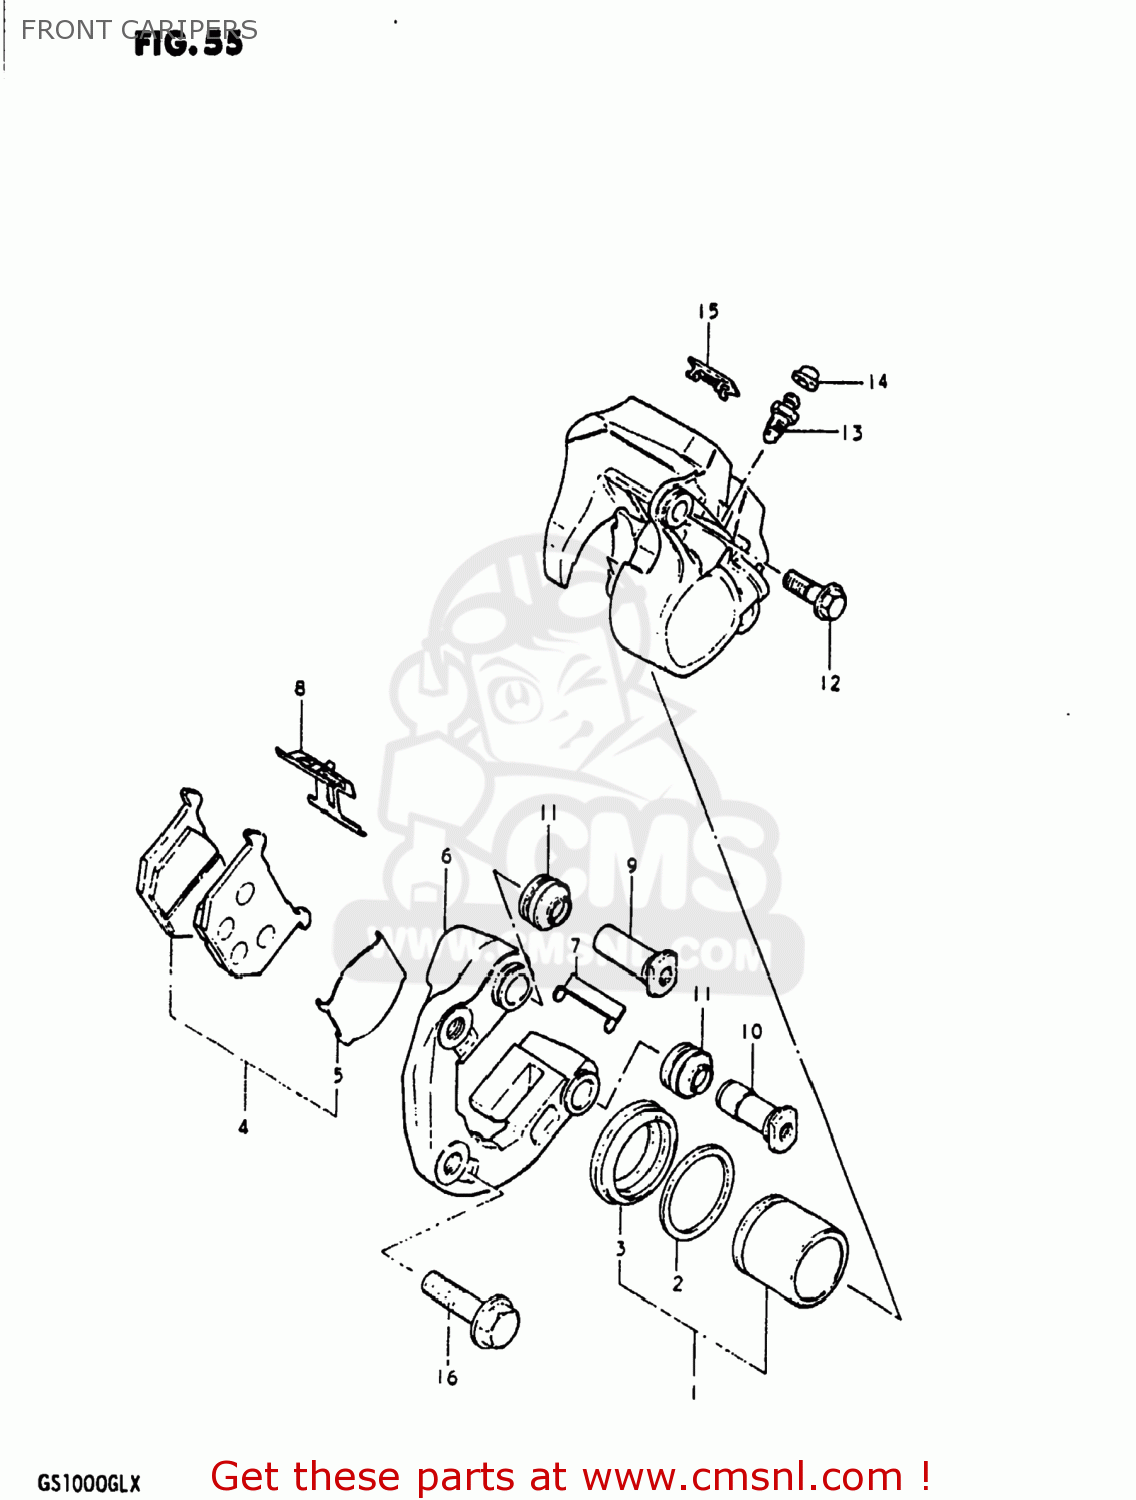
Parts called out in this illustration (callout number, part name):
0	CARIPER ASSEMBLY,RIGHT
1	PISTON SET
2	SEAL,PISTON
3	BOOT,PISTON
4	PAD SET (MCA)
5	SHIM,PAD
6	CARRIER,CALIPER,LEFT
7	GUIDE,PAD
8	SPRING,PAD
9	AXLE NO.1
10	AXLE NO.2
11	BOOT,AXLE
12	BOLT,CALIPER HOUSING
13	BLEEDER
14	CAP,BREATHER
15	COVER,INDICATOR
16	BOLT
